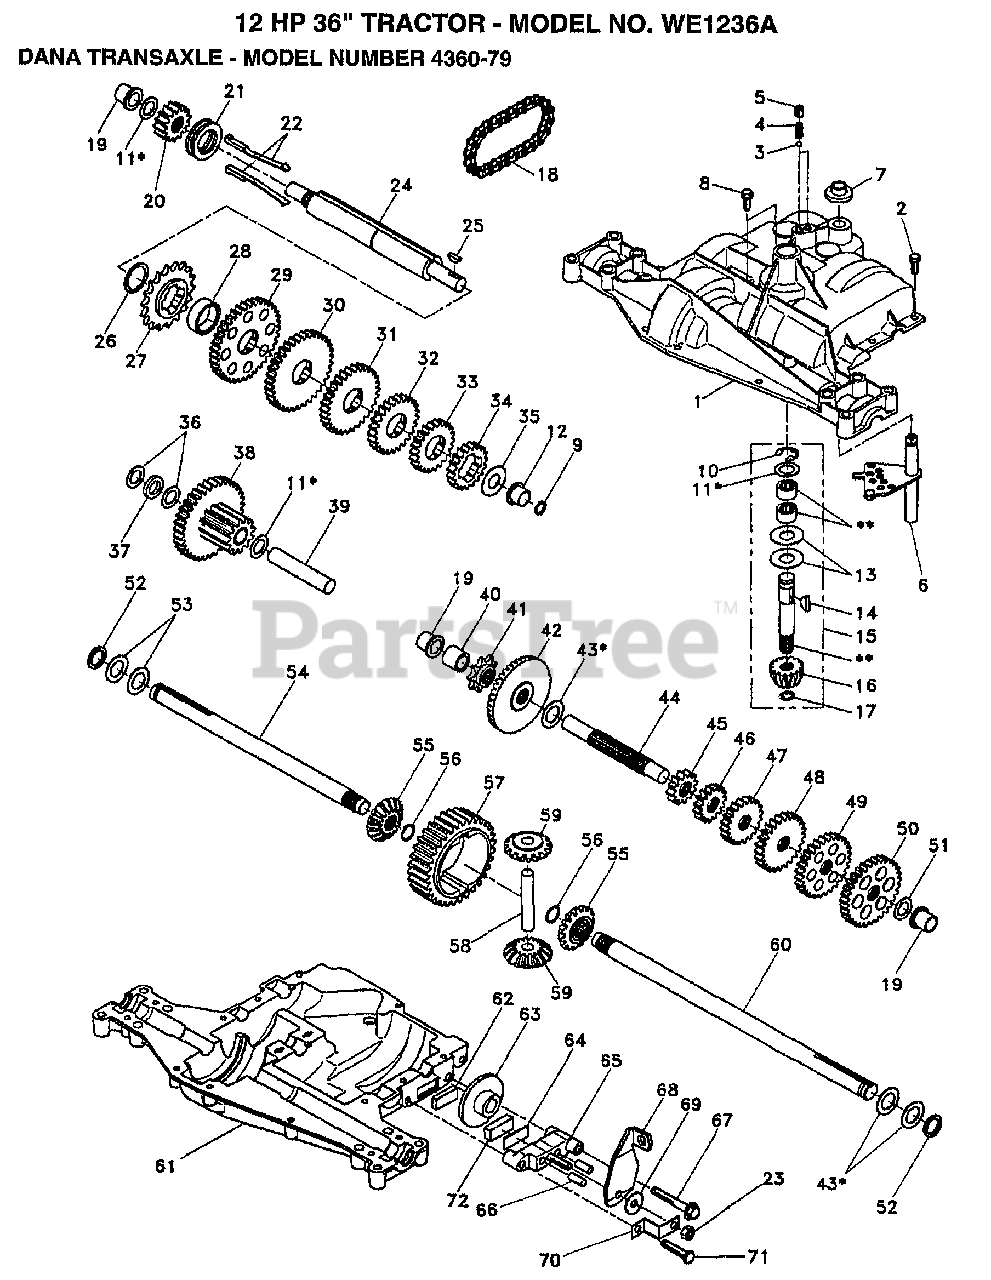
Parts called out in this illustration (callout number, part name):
1	HOUSING UPPER TRN
4	"SPRING, DETENT LT"
5	"SCREW, SET LT"
6	KIT SHIFTER ASM
7	SHIFTER BOOT
8	SCREW TAP W/SEAL
9	SQUARE RING
11	ASM KIT SHIM 4689
12	BEARING FLAN-DANA
13	WASHER T
14	KEY WOODRUFF-DANA
15	AS KIT INPUT SHFT
16	PINION 14T T
17	"RING,RETAINING LT"
18	"CHAIN,24 PTCH LT"
19	BEARING.FLNG.5510
20	GEAR SPUR 14 TTH
21	COLLAR CLUTCH
22	ASM KIT CLTCH KEY
23	NUT.LOCK.5/16-24
24	SHAFT INTERM DANA
25	WOODRUFF KEY
26	"RING,RETAINING LT"
27	SPROCKET 18T T
28	SPACER YT
29	GEAR SPUR 37 TTH
30	GEAR SPUR 35 TTH
32	GEAR 25T LT
33	GEAR SPUR 22 TT
34	SPUR GEAR 19T
35	"WASHER, PLAIN LT"
36	WASHER 025
37	SPACER
38	ASSM GEAR COMB
39	SHAFT IDLER
40	SPACER T
41	SPROCKET 9T LT
43	ASM KIT SHIM
44	SHAFT T
45	GEAR SPUR 12 TTH
46	GEAR SPUR 15 TTH
48	"GEAR, SPUR 25T LT"
49	GEAR 28T T
50	"GEAR, SPUR 31T LT"
51	WASHER 060
52	NEOPRENE WASHER
53	WASHER 031
55	GEAR 15T T
56	"RING,RETAINING LT"
58	SHAFT T
59	GEAR 1ST T
61	HOUSING LOWER TNS
62	PUCK T
63	BRAKE DISC. T
64	SPACER LT
66	PIN T
69	WASHER LT
71	"SCREW, TAPPING LT"
72	PUCK T
